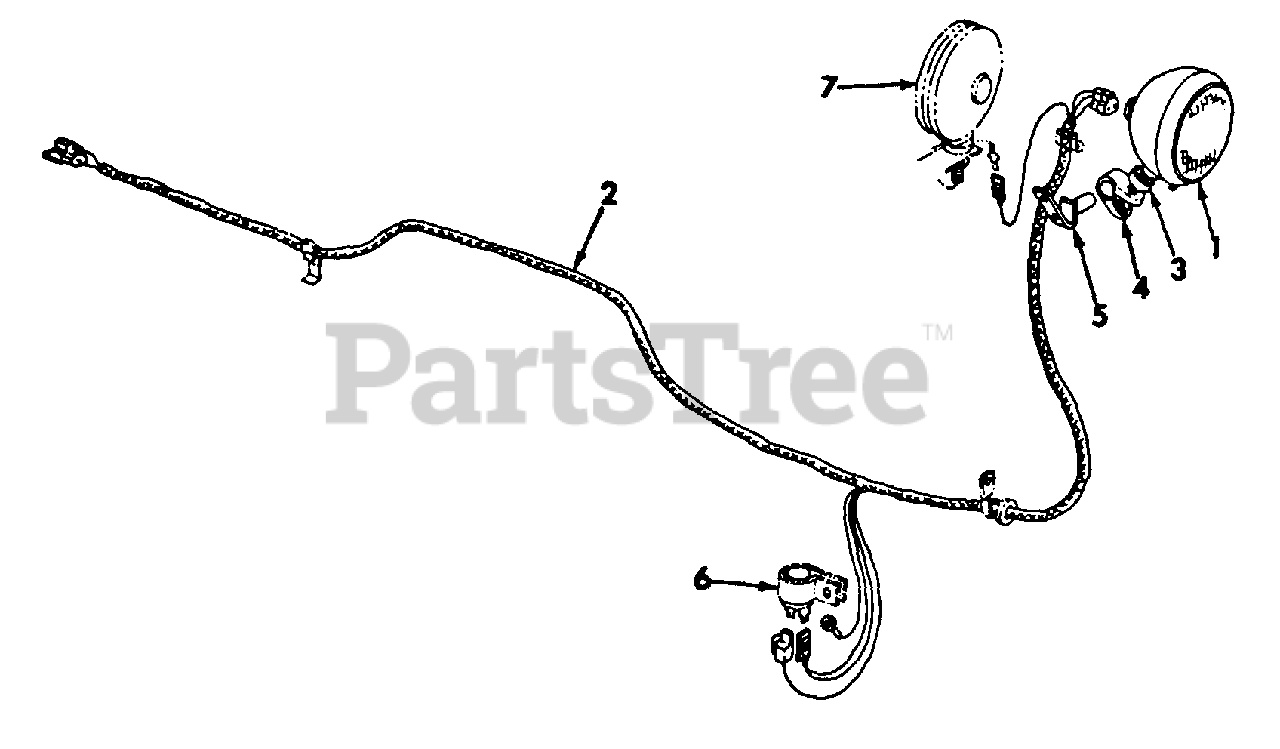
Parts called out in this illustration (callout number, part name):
1	LIGHT ASSY, SEALED BEAM COMBINATION REAR AND TAIL
2	HARNESS ASSY, COMBINATION REAR LIGHT
2	CABLE ASSY, COMBINATION REAR LIGHT-184 TRACTOR
5	BRACKET ASSY, COMBINATION REAR LIGHT
6	FLASHER, WARNING LIGHT
7	LIGHT ASSY, WARNING
